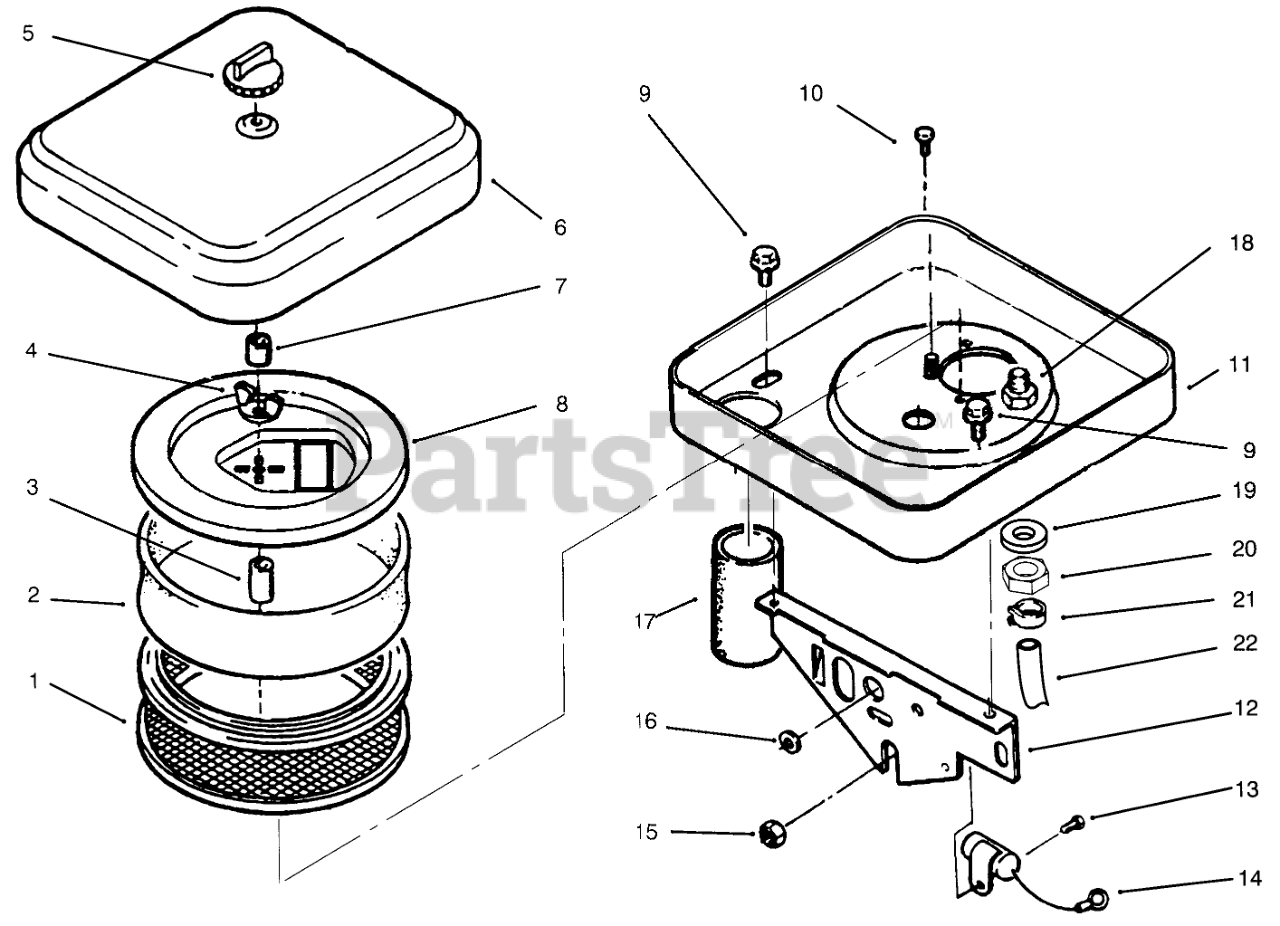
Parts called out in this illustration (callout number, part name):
1	AIR-CLEANER ELEMENT
2	AIR CLEANER ELEMENT
3	SPACER-1" LG
4	1/4-20 WING NUT
6	CHROME-AIR CLEANER
7	SPACER-RUBBER
8	ELEMENT COVER KIT
9	SCREW-TAPPING
10	MACHINE SCREW
11	AIR-CLEANER HOUSING
12	SUPPORT-AIR CLEANER
13	SCREW #10-32 X 5/8
14	CONDENSER
15	WASHER-LOCK
16	GROMMET
17	AIR INTAKE TUBE
18	Fitting-Barbed
19	HOSE FITTING GASKET
20	TAPPET NUT
21	CLAMP-HOSE
